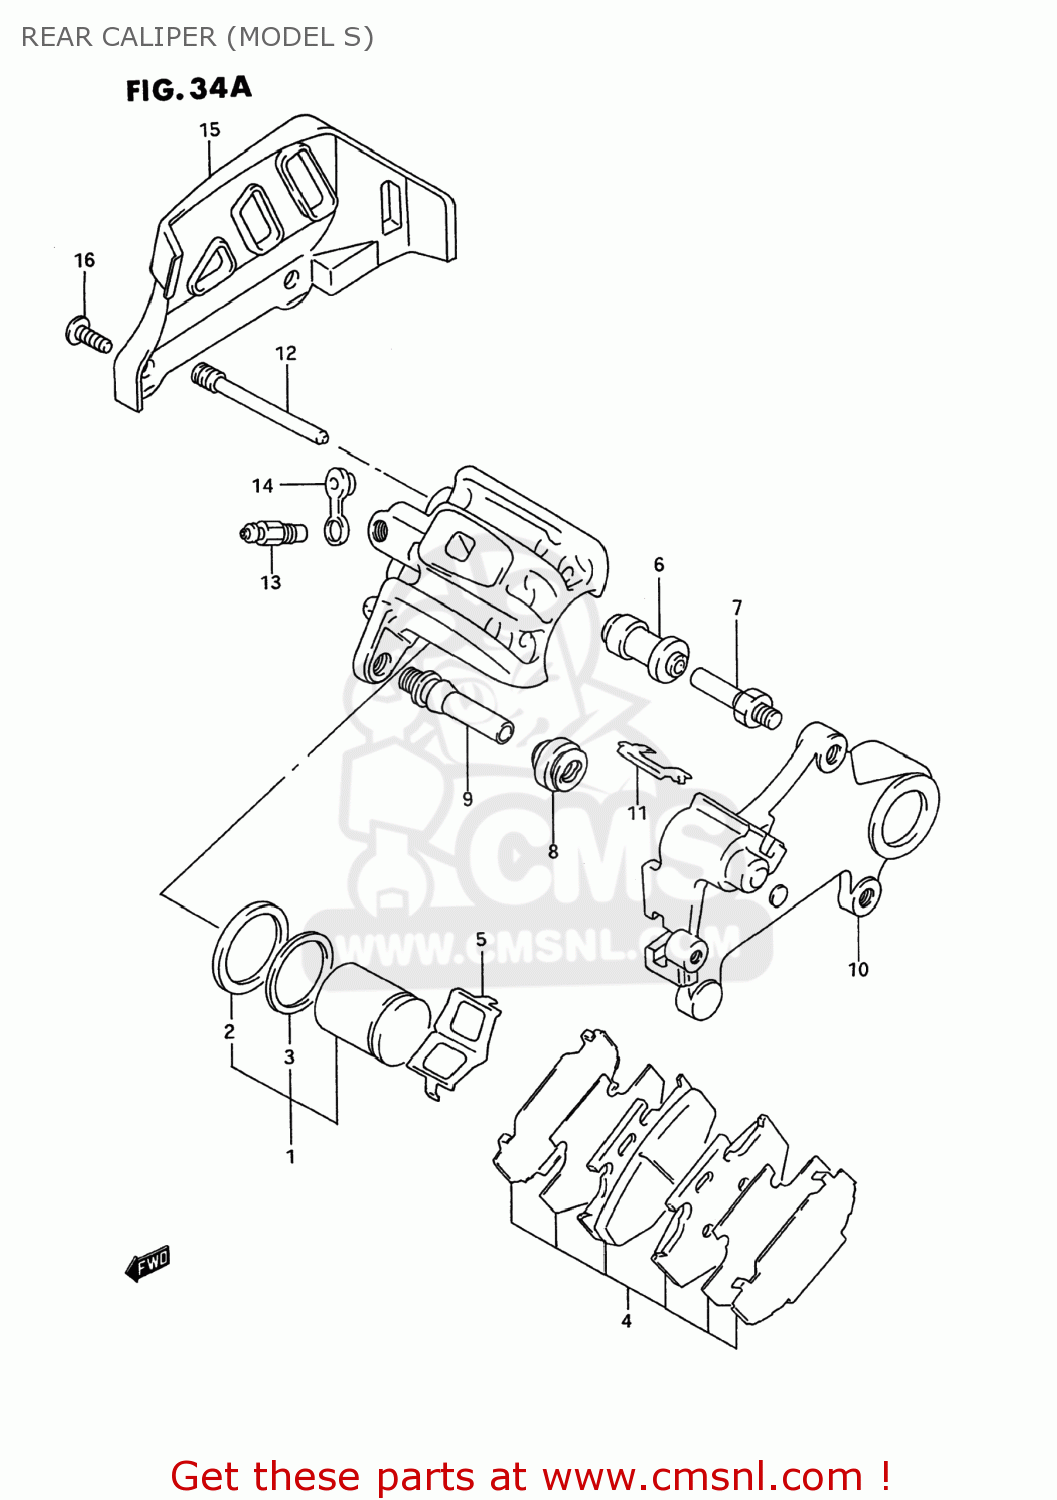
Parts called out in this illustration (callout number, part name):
1	PISTON SET
2	SEAL,PISTON
3	SEAL
4	PAD & SHIM SET (NAS)
5	SPRING,PAD
6	BOOT
7	PIN,BOLT
8	BOOT
9	PIN
10	BRACKET
11	RETAINER,BRACKET
12	PIN,HANGER
13	BLEEDER
14	CAP,BLEEDER
15	GUARD,RR CALIPER
16	SCREW 6X12
